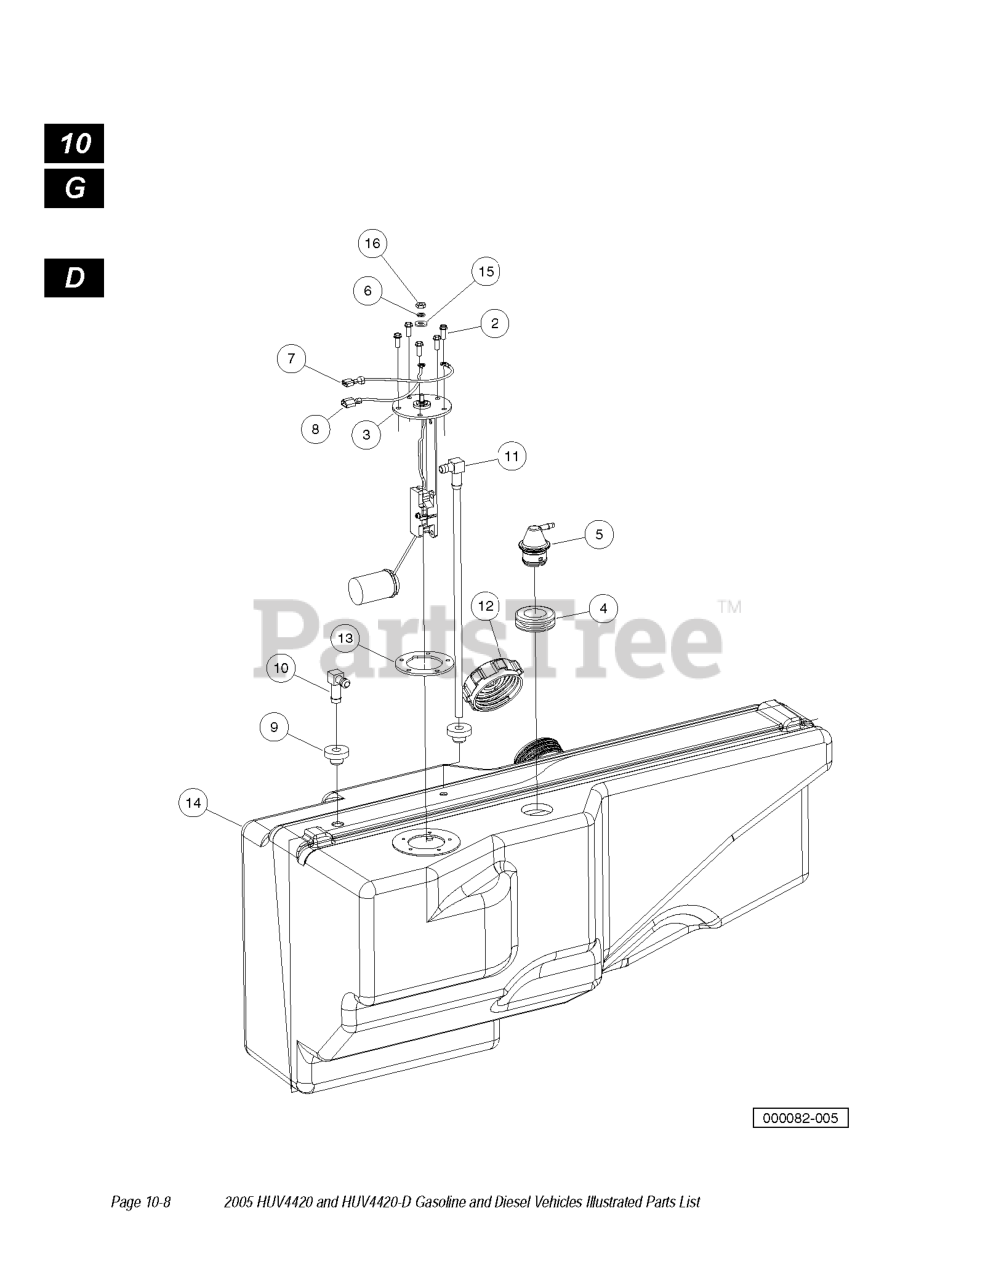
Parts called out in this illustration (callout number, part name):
1	ASM, TANK, DIESEL, SIDEFILL
2	SCREW
4	INSULATION GROMMET
5	FUEL TANK VENT ASSY
6	WASHER,#10 SPLIT WASH
9	BUSHING, LINE, RETURN
10	ELBOW, 90 BARBED
11	PICKUP TUBE, FUEL
12	ASM, CAP, FUEL, DIESEL, PTD
13	GASKET, SEND UNIT (RUBBER)
15	WASHER FLAT
16	NUT, #10-32 BRASS HEX
